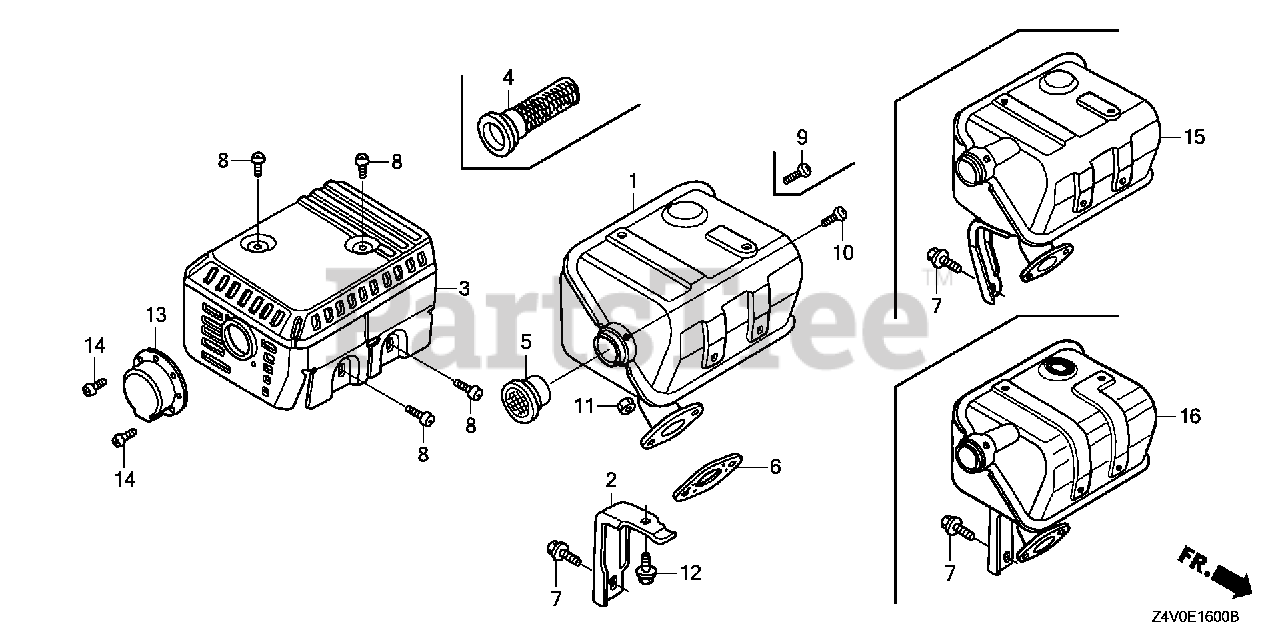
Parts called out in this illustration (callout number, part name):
3	PROTECTOR, MUFFLER
4	ARRESTER, SPARK
6	GASKET, MUFFLER
7	BOLT, FLANGE (6X13)
8	SCREW, TAPPING (5X8)
9	SCREW, TAPPING (4X6) (TO INSTALL OPTIONAL SPARK ARRESTER)
11	NUT, HEX. (8MM)
16	MUFFLER
